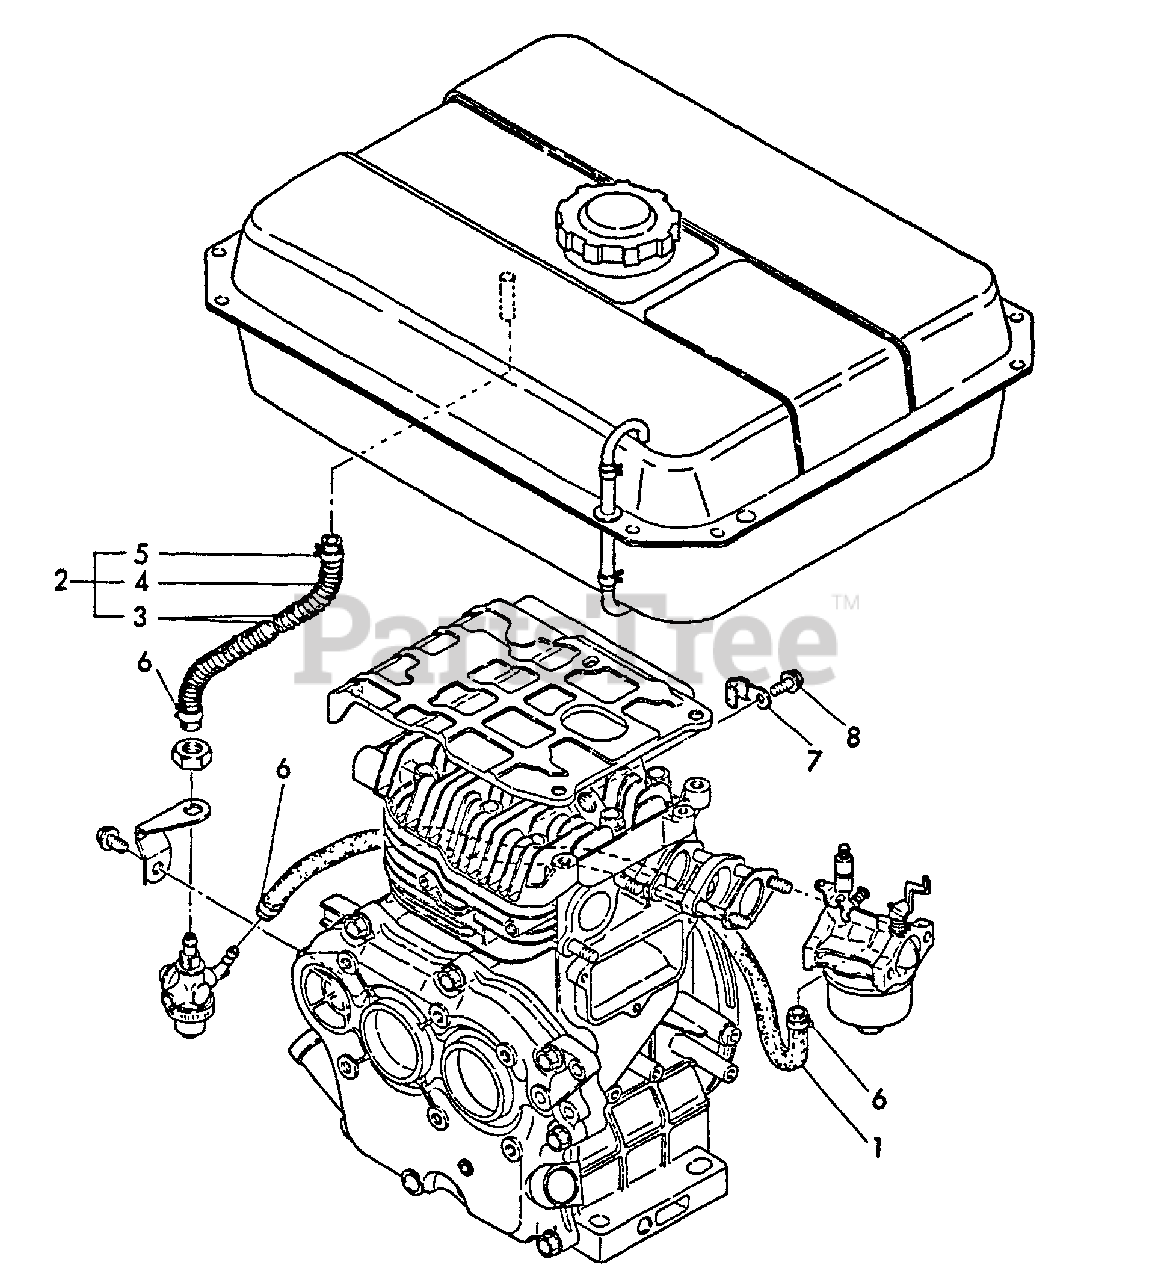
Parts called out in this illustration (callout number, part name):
1	PIPE, FUEL
2	PIPE, FUEL
3	PIPE, FUEL
4	SPRING, PROTECTIVE
5	CLAMP, HOSE - 10
6	CLAMP, HOSE - 10
7	CLAMP
8	BOLT - 6×8 -- PLATED
